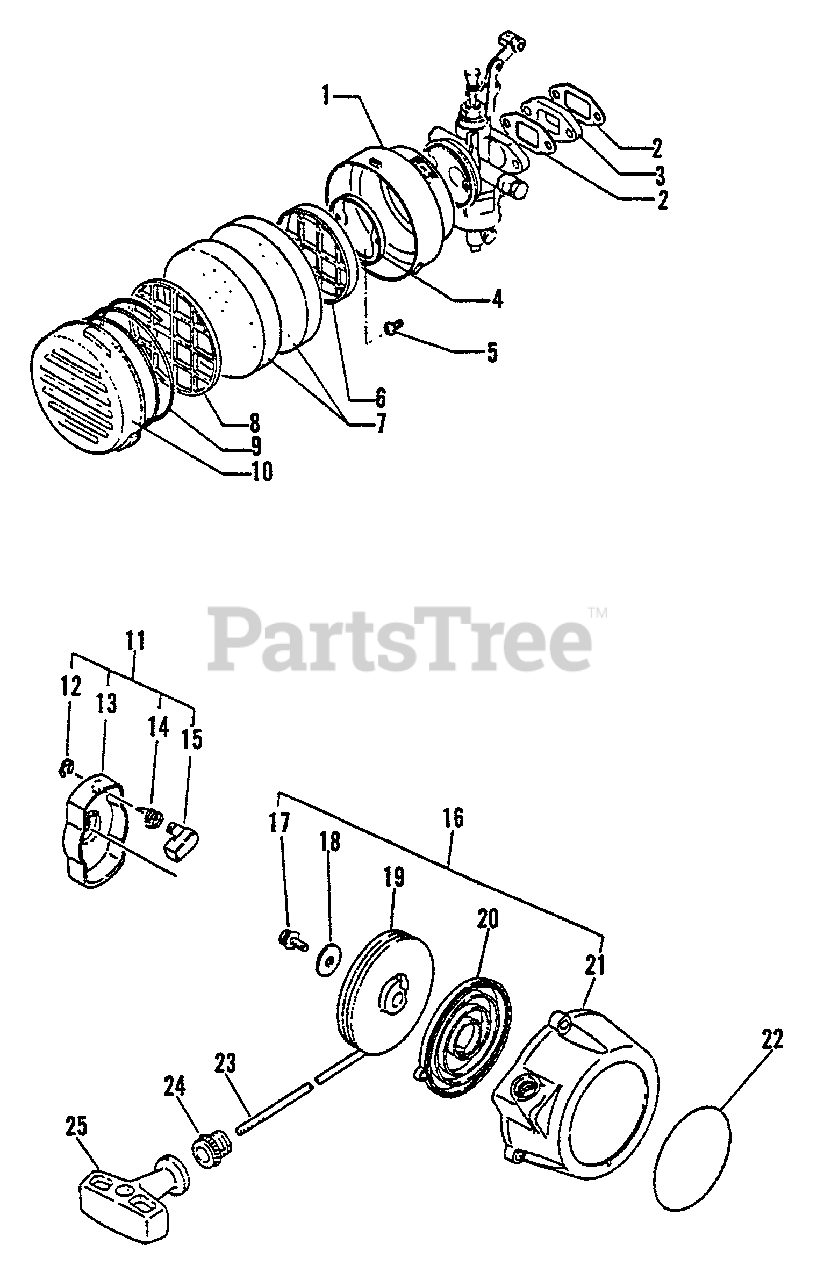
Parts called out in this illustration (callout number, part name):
1	CASE, AIR FILTER
3	INSULATOR
4	BRACKET, AIR FILTER
5	SCREW 4×14
6	GRID, AIR FILTER
7	FILTER, AIR
8	HOLDER, AIR FILTER
9	SPRING, AIR FILTER COVER
10	COVER, AIR FILTER
11	PAWL CATCHER ASSY
12	RING, RETAINING - 6
13	CATCHER, PAWL
14	SPRING, RETURN
15	PAWL, STARTER
16	STARTER ASSY
19	REEL, ROPE
20	SPRING, RECOIL
21	CASE, RECOIL STARTER
22	LABEL, ECHO
22	LABEL - MODEL
23	ROPE, STARTER 4.0×880
24	GUIDE, ROPE
25	GRIP, STARTER
